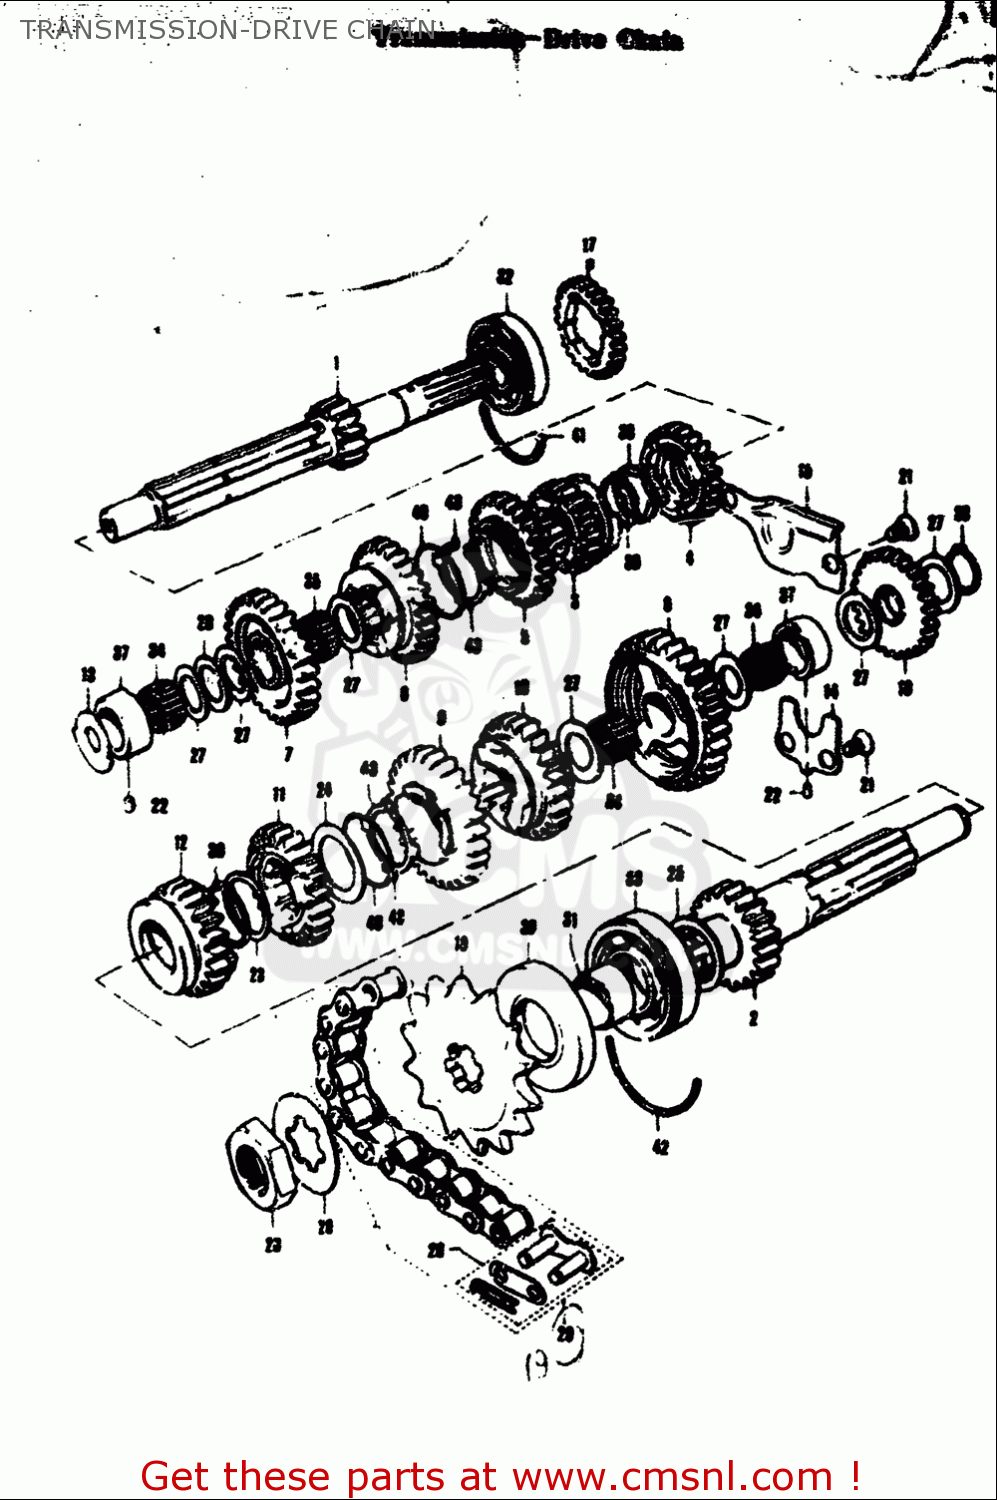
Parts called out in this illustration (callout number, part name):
18	SPROCKET,ENGINE
20	JOINT ASSEMBLY,CHAIN
22	PIN
23	WASHER
24	WASHER
25	WASHER
26	NUT
27	WASHER
28	WASHER(17X29X1)
29	WASHER,LOCK
30	WASHER
31	SPACER (22X27X13.4)
32	BEARING 20X52X15
34	BEARING(17X21X12.8)
35	BEARING(17X21X9.8)
37	BUSHING
38	CIRCLIP
39	RING,SNAP
40	CIRCLIP
